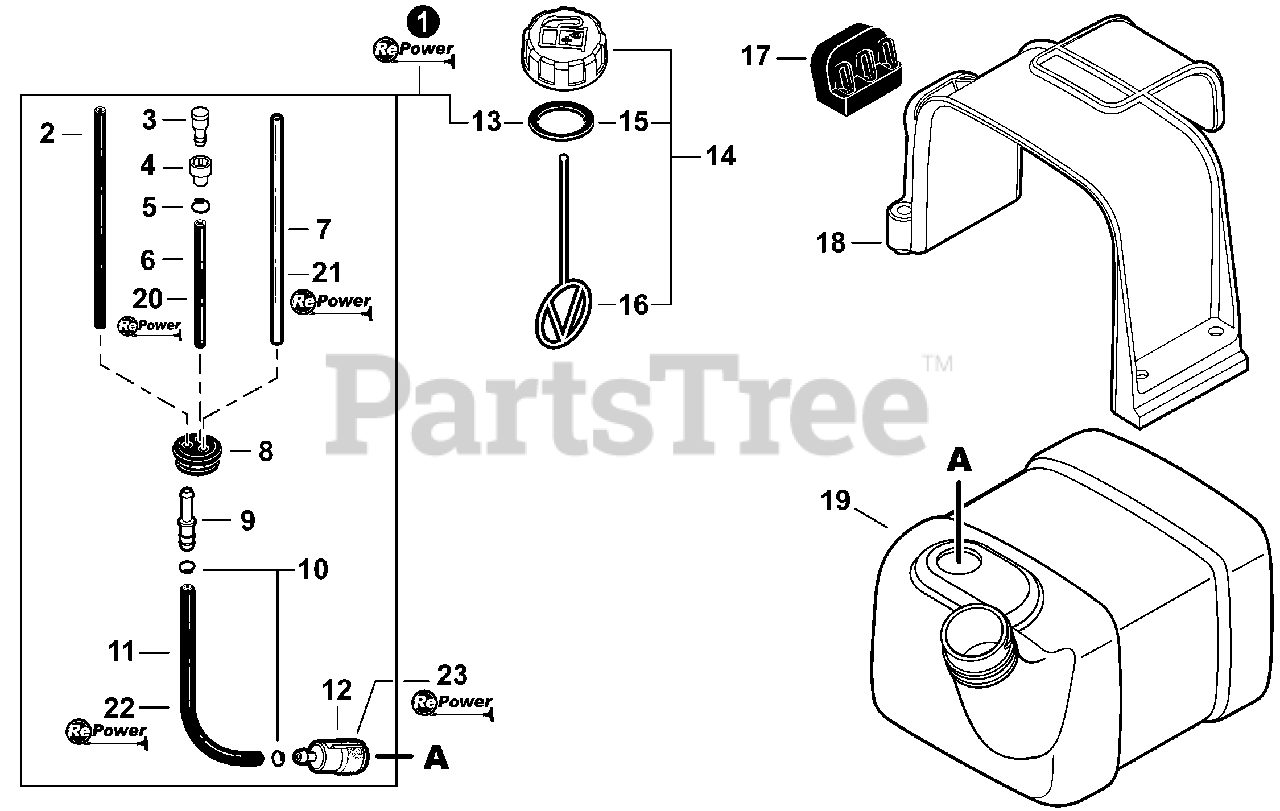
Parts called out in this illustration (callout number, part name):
1	FUEL SYSTEM KIT
2	PIPE, FUEL 3×5×205 BLACK
3	VENT ASSY
4	HOLDER, VENT
5	CLIP Ø6.5 MM
6	PIPE, FUEL 3×6×40 BLACK
7	PIPE 3×6×180 CLEAR
8	GROMMET, FUEL
9	CONNECTOR, PIPE Ø5ר3.5
10	CLIP Ø6
11	PIPE, FUEL 3×5×120 BLACK
12	FILTER, FUEL
13	GASKET, FUEL CAP
14	CAP ASSY, FUEL
15	GASKET, FUEL CAP
16	CONNECTOR, CAP L= 100 MM
17	CUSHION
18	RETAINER, FUEL TANK
19	TANK, FUEL
20	BULK PIPE - 3×6 MM BLACK (4 PIECES×2 M)
21	BULK PIPE - 3×6 MM CLEAR (4 PIECES×2 M)
22	BULK PIPE - 3×5 MM BLACK (4 PIECES×2 M)
23	TUNE-UP KIT - REPOWER
